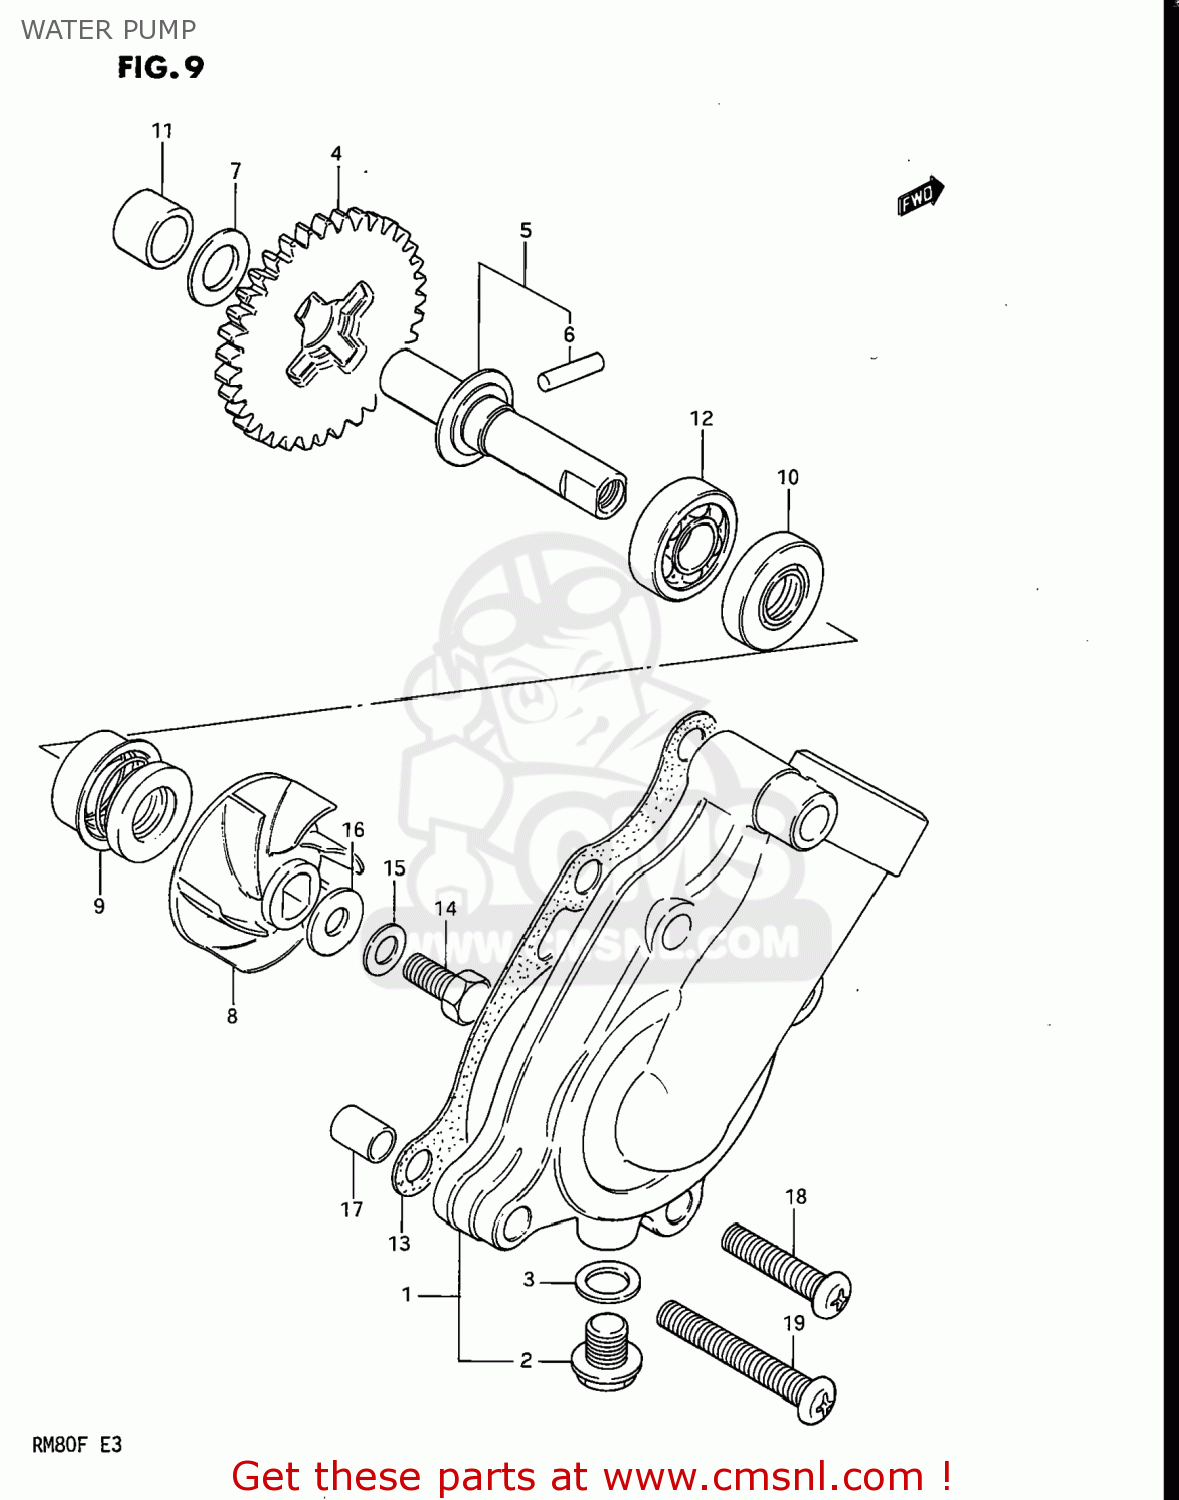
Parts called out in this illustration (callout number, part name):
1	CASE,WATER PUMP
2	BOLT,DRAIN
3	GASKET,DRAIN (NAS)
4	GEAR, DRIVEN (NT:35)
5	SHAFT,WATER PUMP
6	PIN (4X20.8)
7	WASHER,THRUST
8	IMPELLER,WATER PUMP
9	SEAL,WATER PUMP SHAFT
10	SEAL,OIL(10X21X5)
11	BUSH
12	BEARING
13	GASKET,WATER PUMP CASE (MCA)
14	BOLT(6X13)
15	WASHER
16	GASKET (NAS)
17	PIN
18	SCREW
19	SCREW
